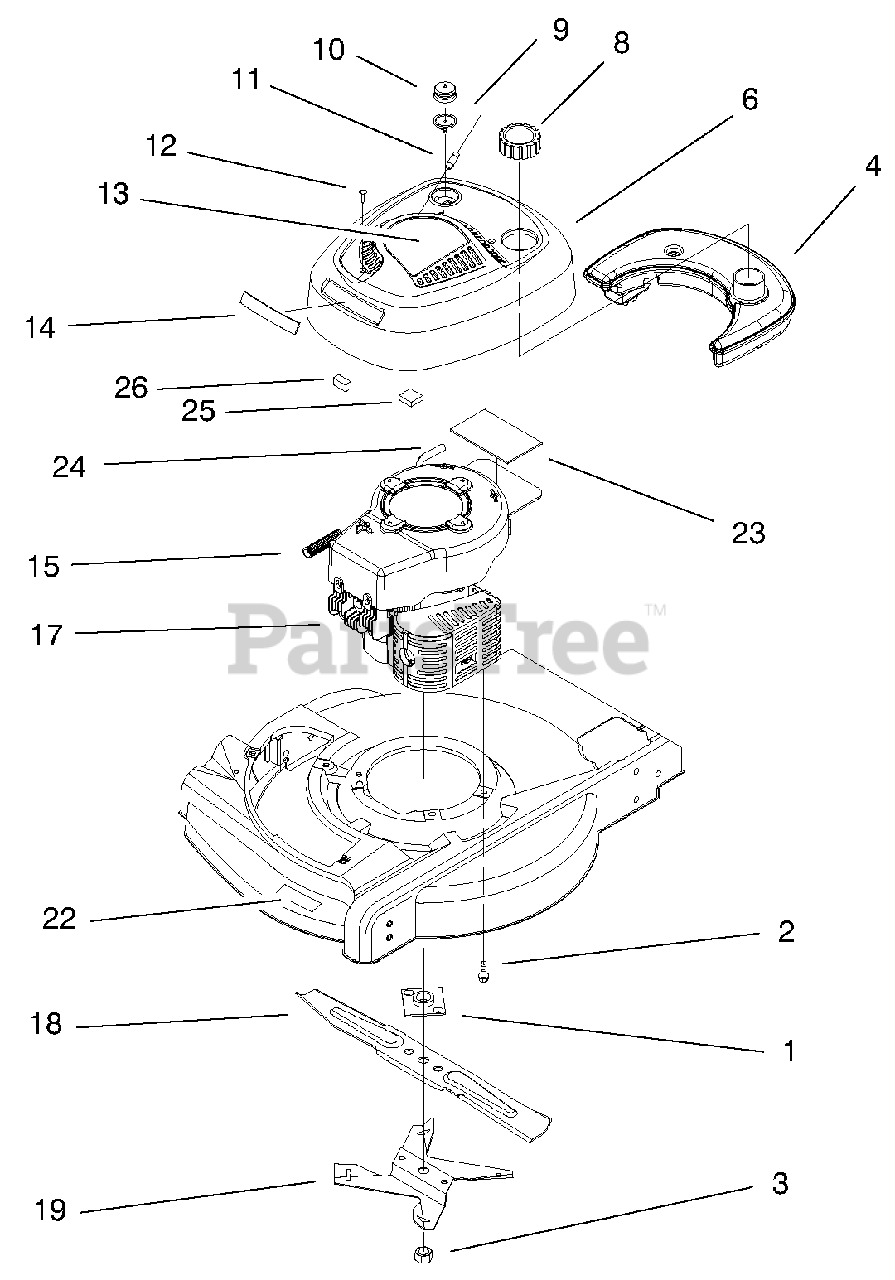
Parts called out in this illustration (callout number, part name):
1	ASM-Plate & Collar
3	Nut-Blade
4	Gas Tank
6	ASM-Shroud & Recoil Covr
8	ASM-Fuel/Oil Cap
9	Bulb-Primer
10	Body-Primer
11	Rope-Stop
12	Screw-Tf Acorn Hd
13	Decal-Recoil
14	Applique-Shroud
15	Spring-Compression
17	Engine ASM Recoil Sp
18	Blade-21" Whirl
19	Fan-Mulching
20	Screw-Throttle Cable
21	Nut-Throttle Cable
22	Decal-Deck
23	Foam Pad
24	Gas Line
25	Foam Strip
26	Foam Strip
